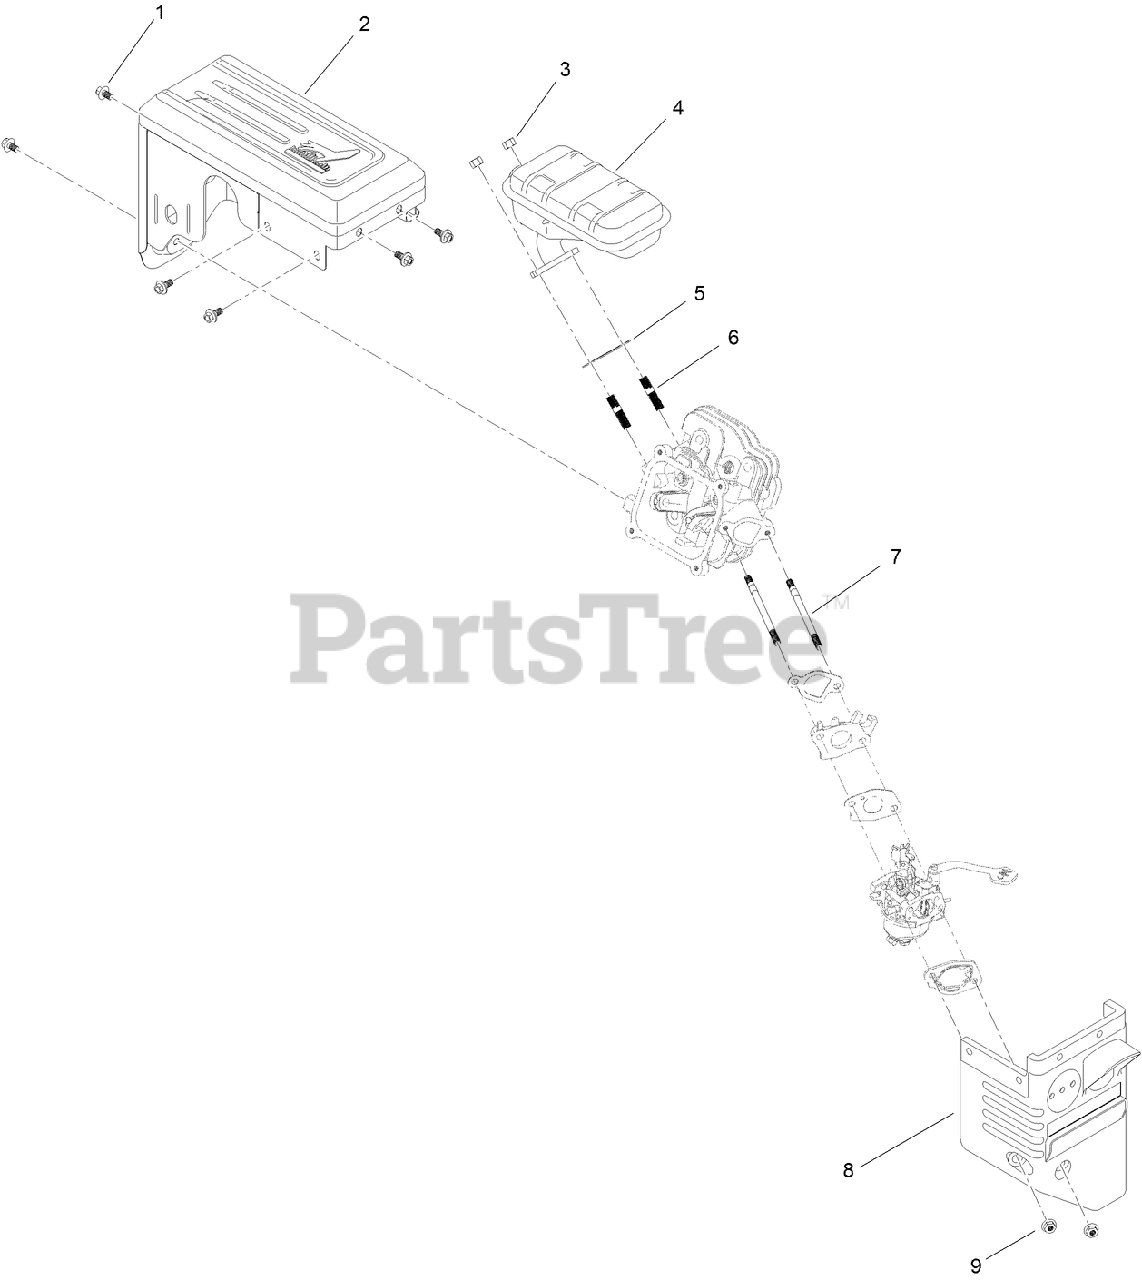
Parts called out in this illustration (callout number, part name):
1	SCREW-HHF
2	MUFFLER SHROUD ASM
3	NUT-HH
4	MUFFLER ASM
5	GASKET-EXHAUST
6	STUD-EXHAUST
7	STUD-INTAKE
8	BOX-HEATER
9	NUT-FLANGE
